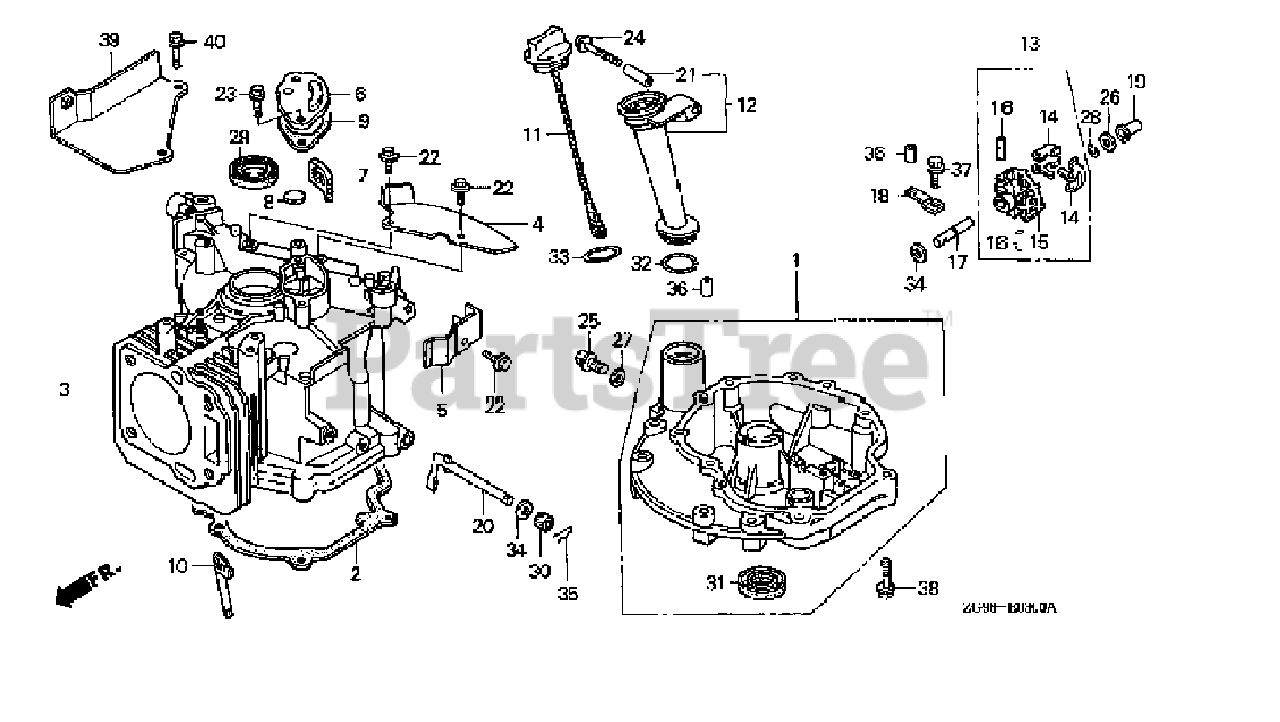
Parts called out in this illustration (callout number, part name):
1	PAN ASSY., OIL (KARCHER)
2	GASKET, OIL PAN (HPE)
3	CYLINDER
4	PLATE A, GUIDE
5	PLATE B, GUIDE
6	CAP, BREATHER CHAMBER
7	FILTER, BREATHER
8	VALVE, BREATHER
9	GASKET, BREATHER CHAMBER
10	PIPE, OIL DEFENSE
11	DIPSTICK, OIL
12	EXTENSION, OIL FILLER (106MM)
13	GOVERNOR ASSY.
14	WEIGHT, GOVERNOR
15	HOLDER, GOVERNOR WEIGHT
16	PIN, GOVERNOR WEIGHT
17	SHAFT, GOVERNOR HOLDER
18	PLATE, GOVERNOR SHAFT HOLDER
19	SLIDER, GOVERNOR
20	SHAFT, GOVERNOR ARM
21	COLLAR, EXTENSION
22	BOLT, FLANGE (6X12) (CT200)
23	BOLT, FLANGE (6X14)
24	BOLT, FLANGE (6X32)
25	BOLT, DRAIN PLUG
26	WASHER, THRUST (6MM)
27	WASHER, DRAIN PLUG (10.2MM)
28	CLIP, GOVERNOR HOLDER
29	OIL SEAL (22X35X6)
30	OIL SEAL (6X11X4)
31	OIL SEAL (25X38X7)
32	O-RING (22.5X2.2)
33	O-RING (26X2.7)
34	WASHER, PLAIN (6MM)
35	PIN, LOCK (8MM)
36	PIN A, DOWEL (8X14)
37	BOLT, FLANGE (6X12)
38	BOLT, FLANGE (6X28)
39	PLATE, GUIDE
40	BOLT, FLANGE (6X20)
